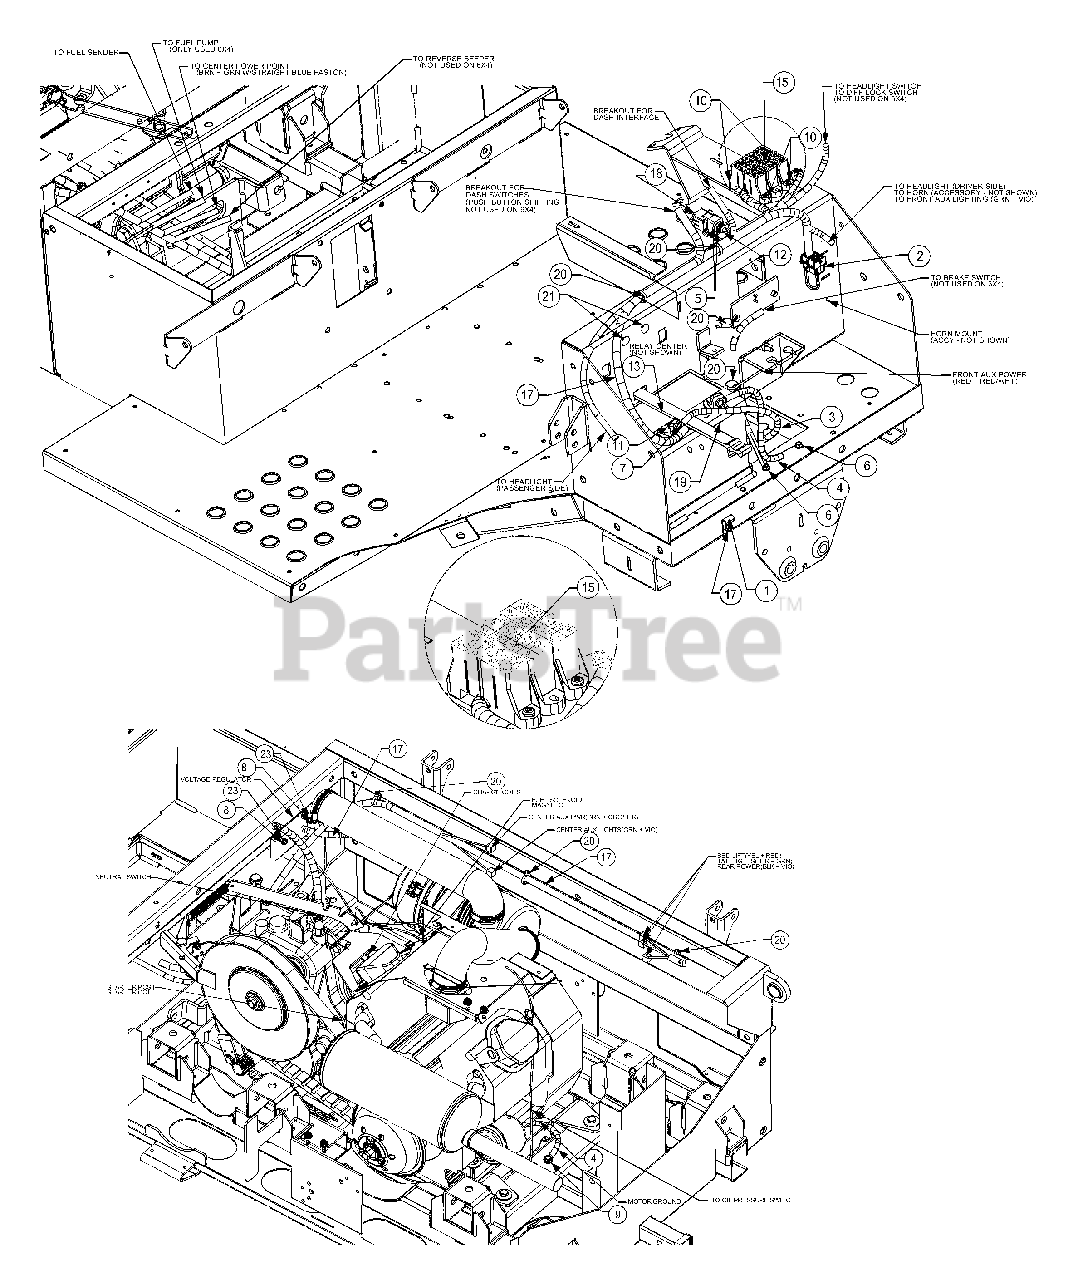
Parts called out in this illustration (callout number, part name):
1	Bracket, Retainer Hook
2	Connection Assembly
3	Harness Assembly, Utility Starter
4	Harness Assembly, Ground
5	Screw, Self-tapping 1/4-20
6	Screw, Self-tapping, 1/4-20 x 0.500
7	Screw, Hex Carriage, 1/4-20 x .75
8	Screw, Self-tapping, 1/4-20 x 1.000
9	Screw, 5/16-18 x.75
10	Screw, #10-24 x 0.75
11	Nut, Hex Sems, 1/4-20
12	Cover, Protection
13	Strap, Battery
14	Cable, Tie 3/16 x.05 x 7.4
15	Fuse, 5 Amp
16	Harness, Utility Wire
17	Harness, Motor Wire
18	Switch, Interlock
19	Battery, 300 CCA
20	Cable Tie, 19" x 8.39"
21	Clip, Ratchet.250 Dia.
22	Heat Shield Cable Clip
23	Lock Washer, 1/4
